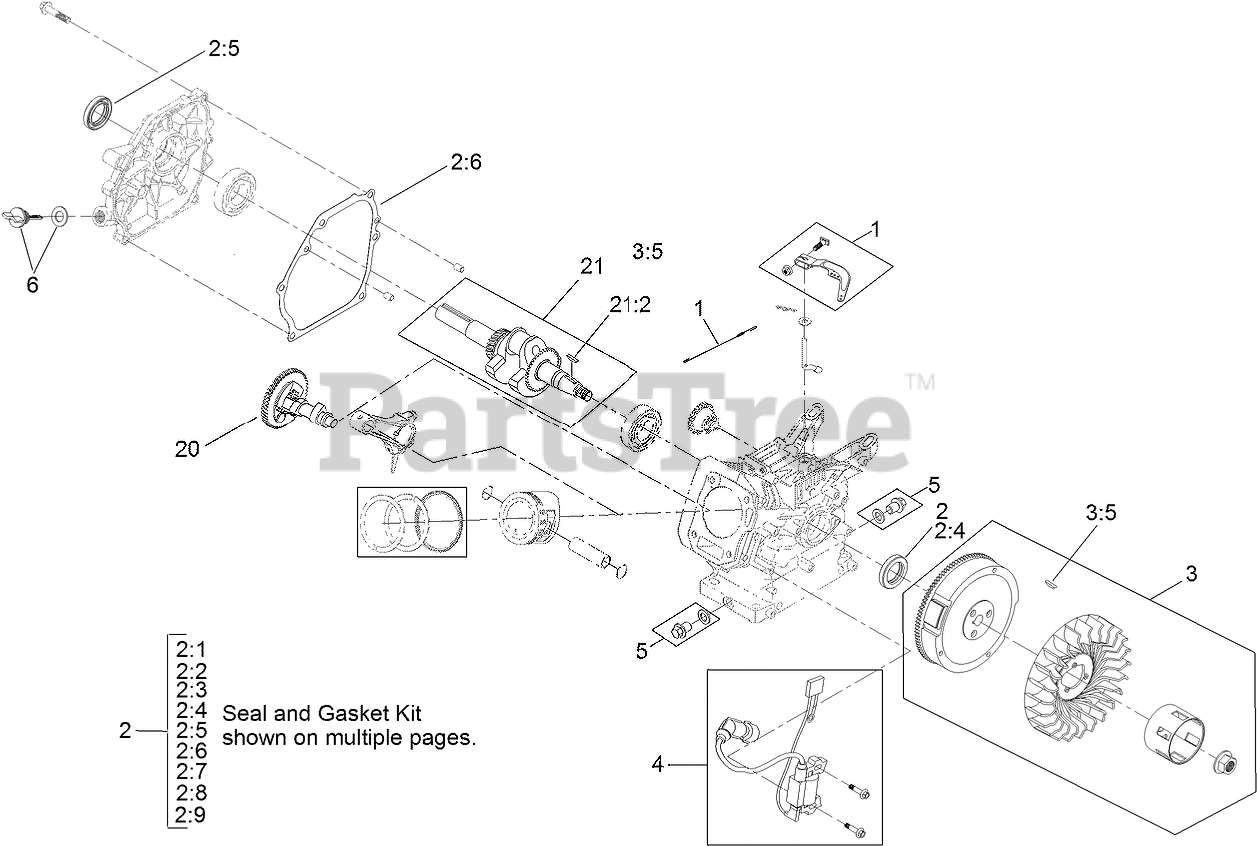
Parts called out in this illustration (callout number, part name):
1	GOVERNOR KIT
2	GASKET AND SEAL KIT
2:1	GASKET-COVER, VALVE
2:2	GASKET-EXHAUST
2:3	GASKET-HEAD, CYLINDER
2:5	SEAL-OIL
2:6	GASKET-COVER, CRANKCASE
2:7	GASKET-CARBURETOR
2:8	GASKET-CARBURETOR
2:9	GASKET-CARBURETOR
3	FLYWHEEL KIT
3:5	KEY-WOODRUFF
4	IGNITION KIT
5	DRAIN PLUG KIT
6	DIPSTICK AND O-RING KIT
20	CAMSHAFT
21	Loose Parts Package
21:2	KEY-WOODRUFF
